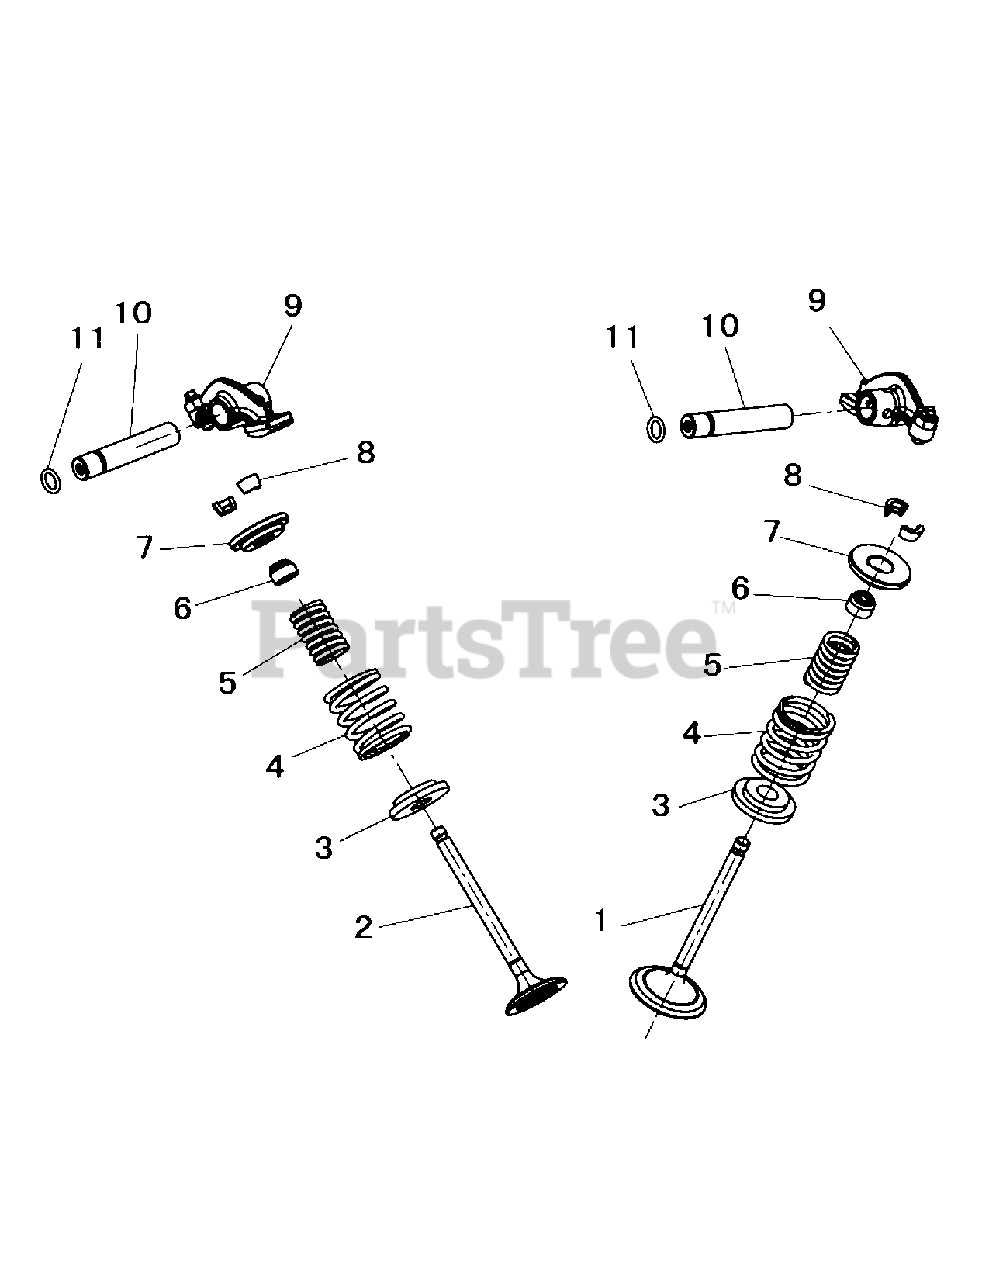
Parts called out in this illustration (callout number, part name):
3	Spring Seat-Valve
4	Spring-Outer Valve
5	Spring-Inner Valve
6	Fuel Shield Cover Comp
7	Cotter Seat-Valve
8	Lock Clip-Valve
9	Rocker Arm
10	Rocker Arm Shaft I
